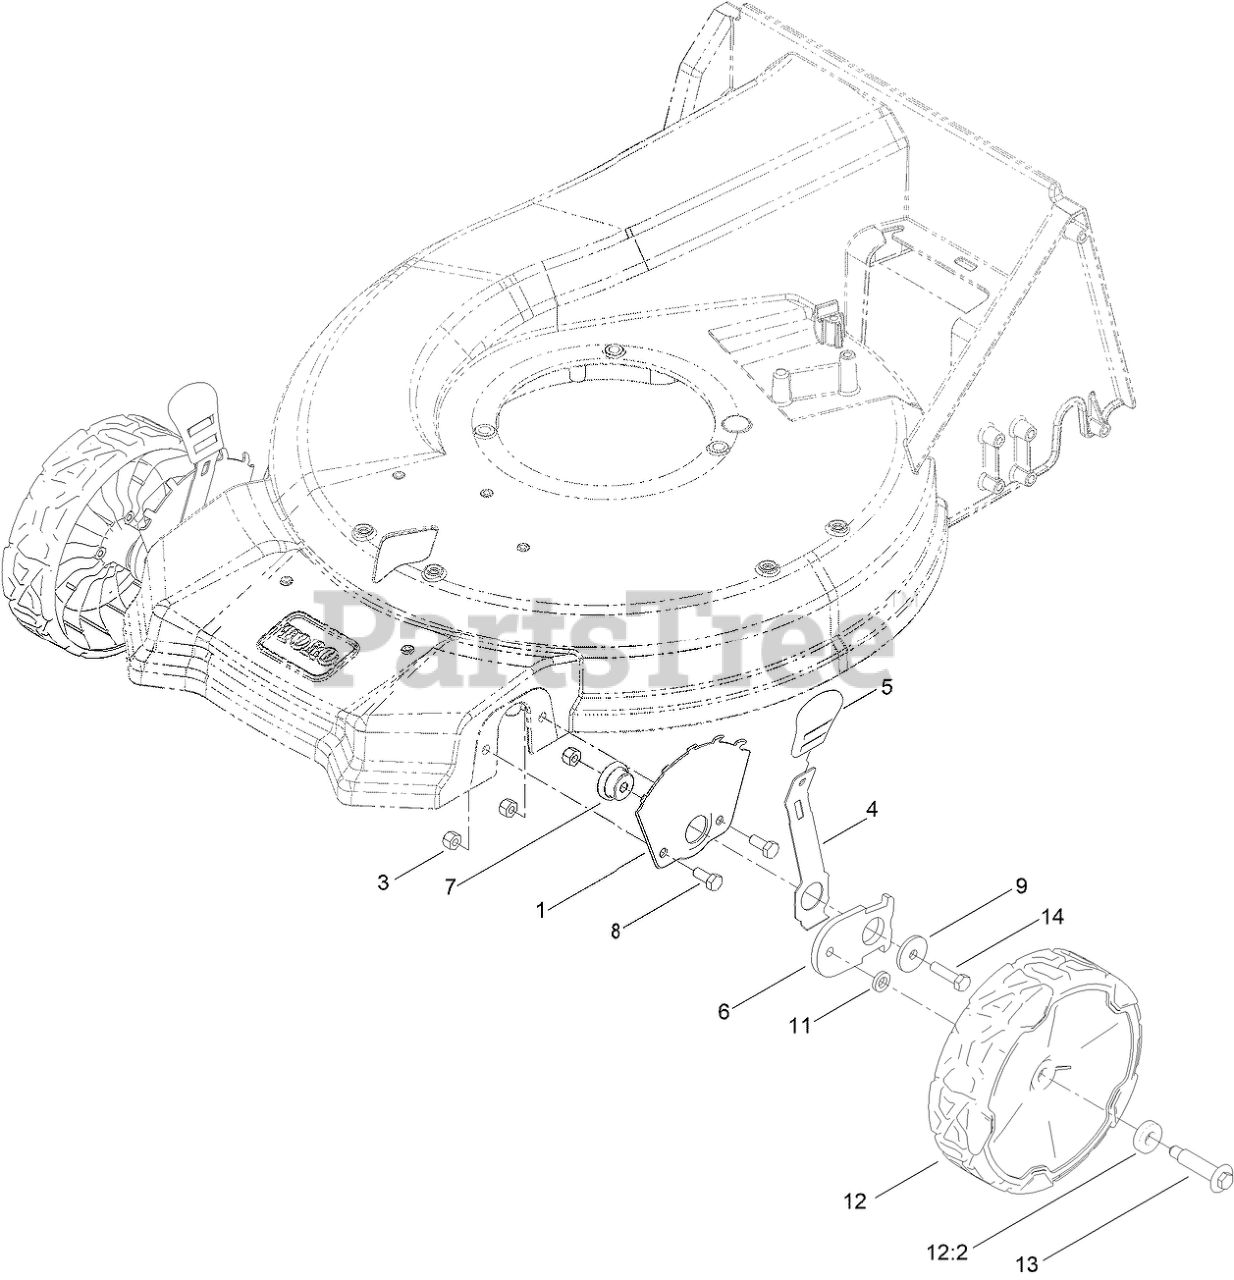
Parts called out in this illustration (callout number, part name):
1	PLATE-HOC,FRONT FSVQ WEDNESDAY
3	NUT-LOCK, NI
4	ARM-SPRING
5	KNOB-HOC
6	ARM-PIVOT, FRONT
7	BUSHING-MOUNT, HOC
8	SCREW-HH
9	WASHER-FLAT
11	WASHER-WHEEL BOLT
12	ASM-WHEEL, 8" (BEARINGS)
12:2	BEARING-WHEEL
13	WHEEL BOLT
14	SCREW-HH
